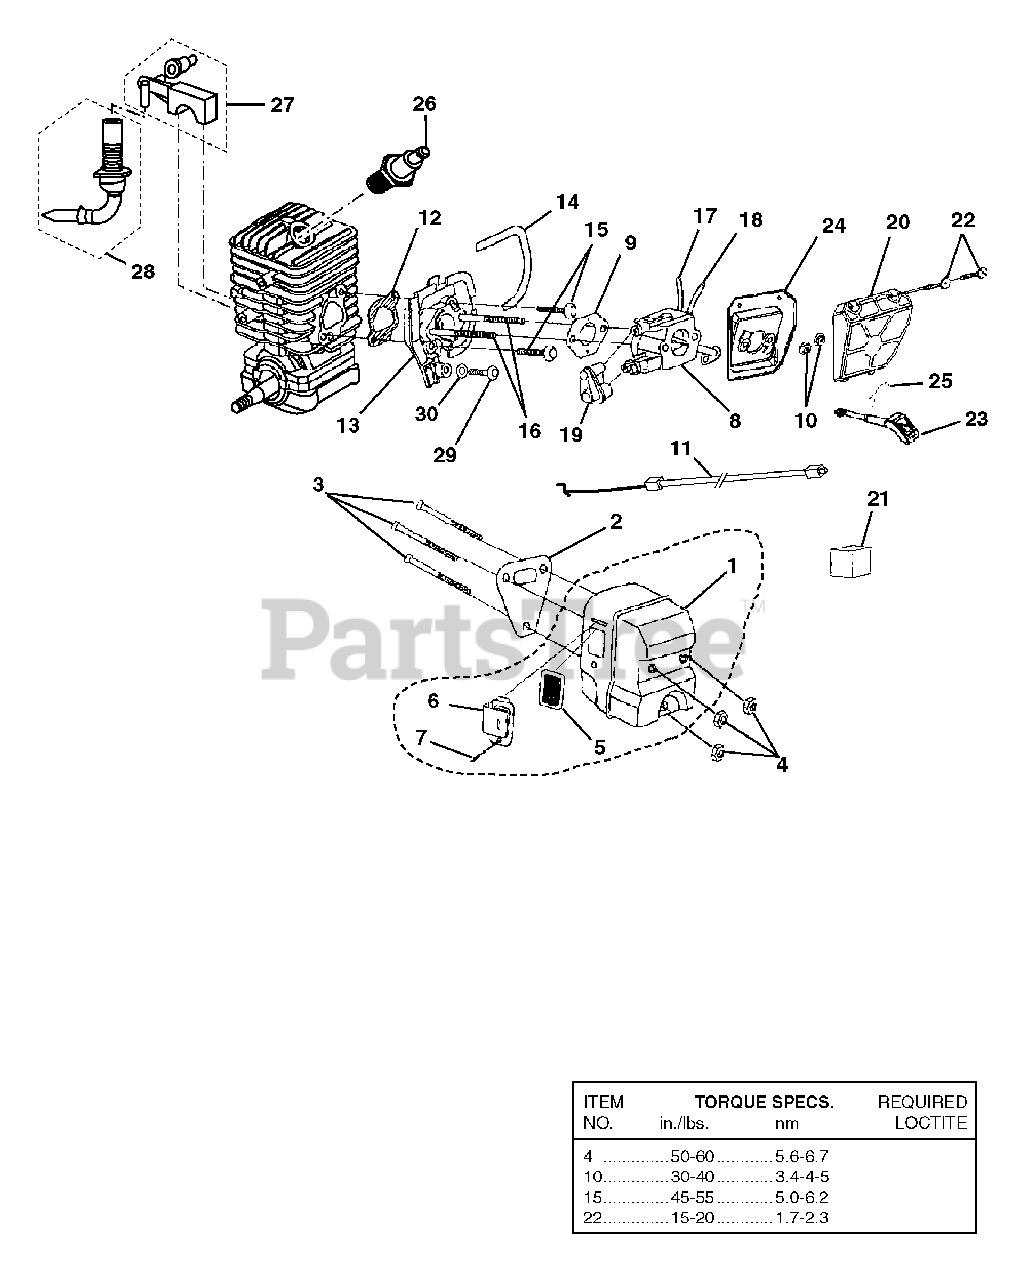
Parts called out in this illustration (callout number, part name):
1	MUFFLER
2	MUFFLER GASKET
3	SCREW-SQUARE HD.
4	NUT-LOCKING HEX (10-32)
5	SCREEN, SPARK
6	DEFLECTOR, MUFFLER
7	SCREW (8-32 x.312)
8	CARBURETOR
9	CARBURETOR GASKET
10	FLANGE NUT (10-24)
11	THROTTLE CABLE
12	GASKET, HEAT DAM
13	HEAT DAM
14	SEAL, HEAT DAM
15	SCREW, TRUSS HD. (10-24 x 7/8 in.)
16	SCREW, CARBURETOR
17	FUEL LINE (TANK TO CARB. 8-1/2 in.)
18	FUEL LINE (GARB. TO PURGE BULB 4 in.)
19	CARBURETOR GROMMET
20	AIR FILTER COVER
21	PRE FILTER (IN ENGINE HOUSING)
22	SCREW, SLOTTED PAN HD. (8-16 x 5/8 in.)
23	ROD, CHOKE
24	AIR FILTER PLATE
25	SPRING CLIP (CHOKE ROD)
26	SPARK PLUG
27	OIL PUMP ASSY.
28	OIL INTAKE W/FILTER
29	SCREW THREAD FORMING (10 -14 x.5)
30	WASHER, RETAINING
